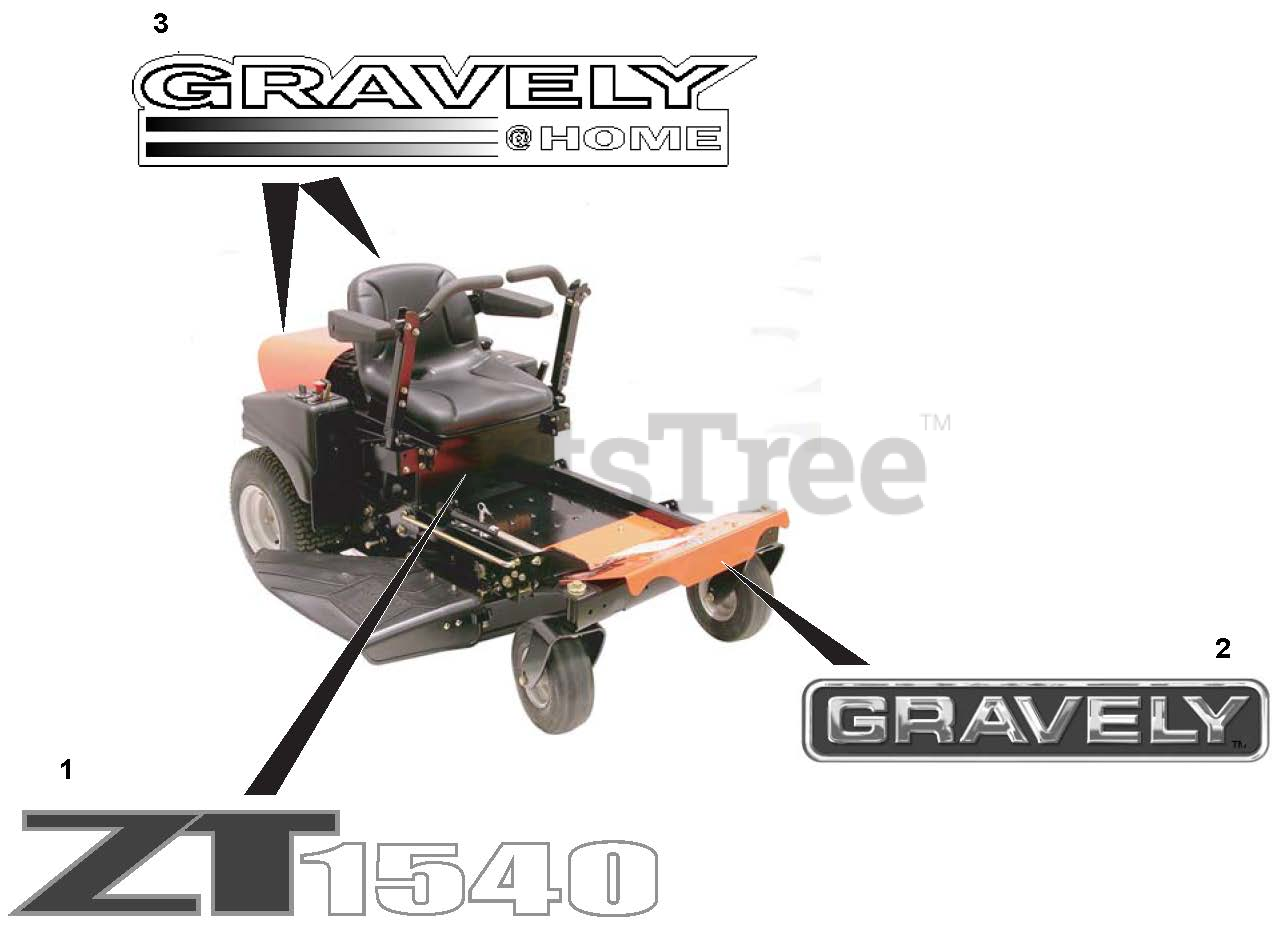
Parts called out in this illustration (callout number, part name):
1	Decal, Mini ZT 1434
1	Decal, Mini ZT 1540
2	Decal, Gravely Jewel
3	Decal, Gravely @ Home
